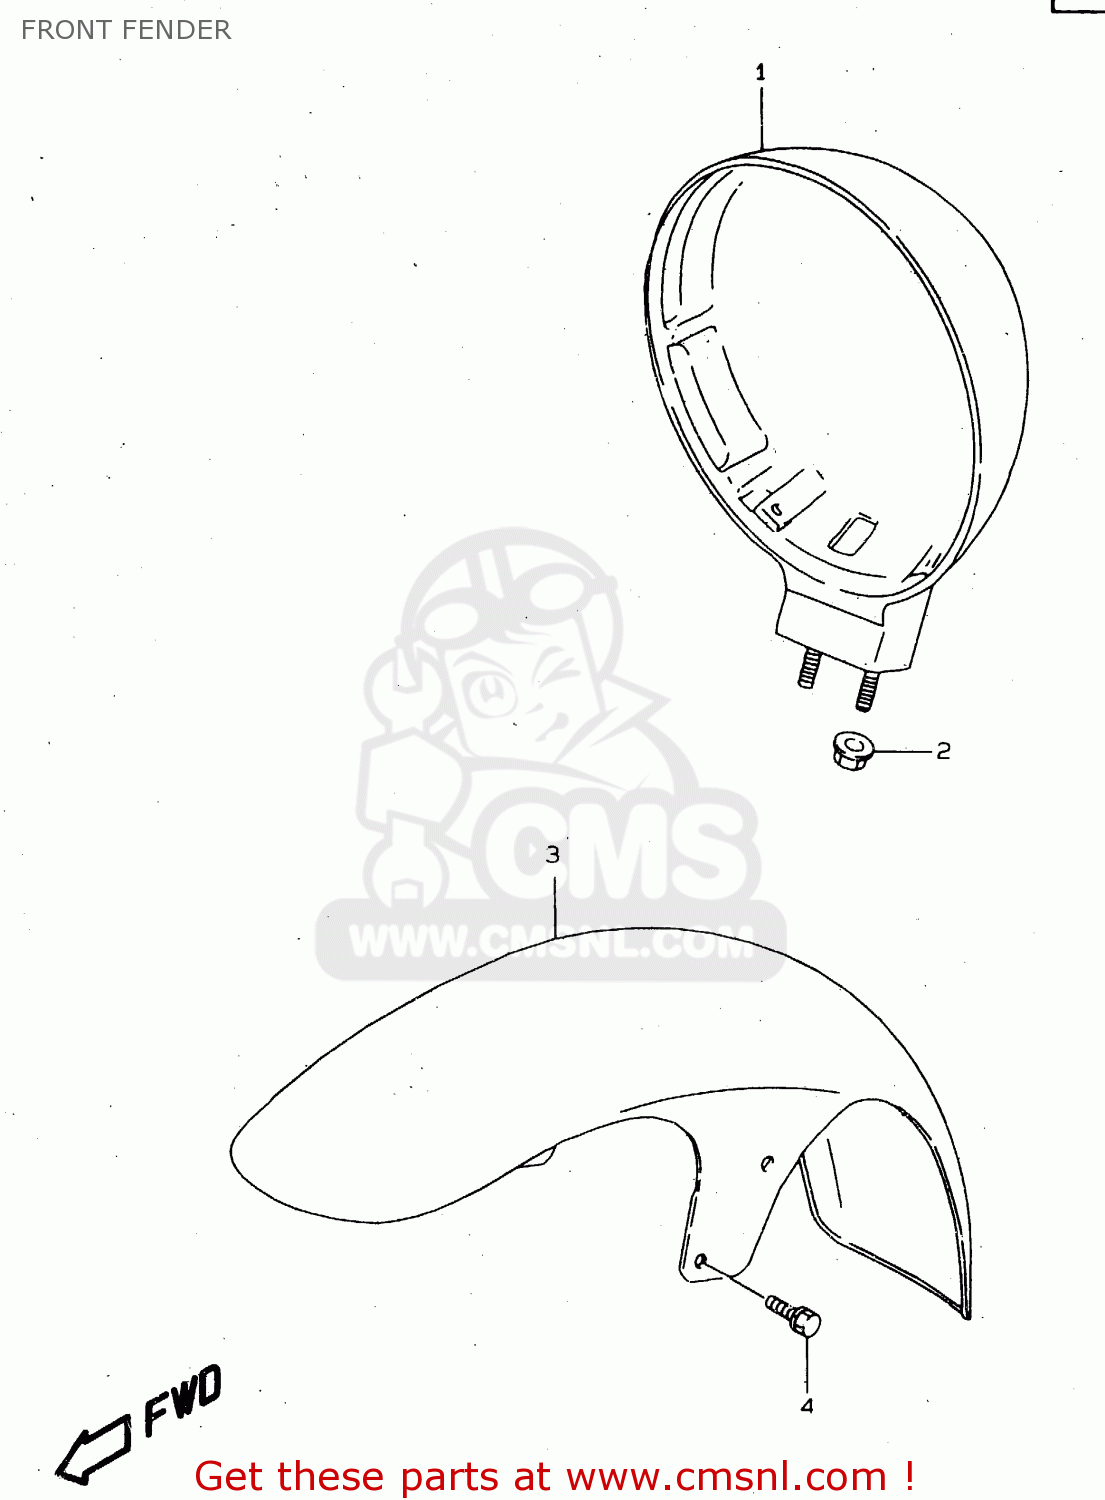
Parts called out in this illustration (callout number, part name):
1	HOUSING,HEADLAMP
2	NUT
3	FENDER,FR
4	BOLT
